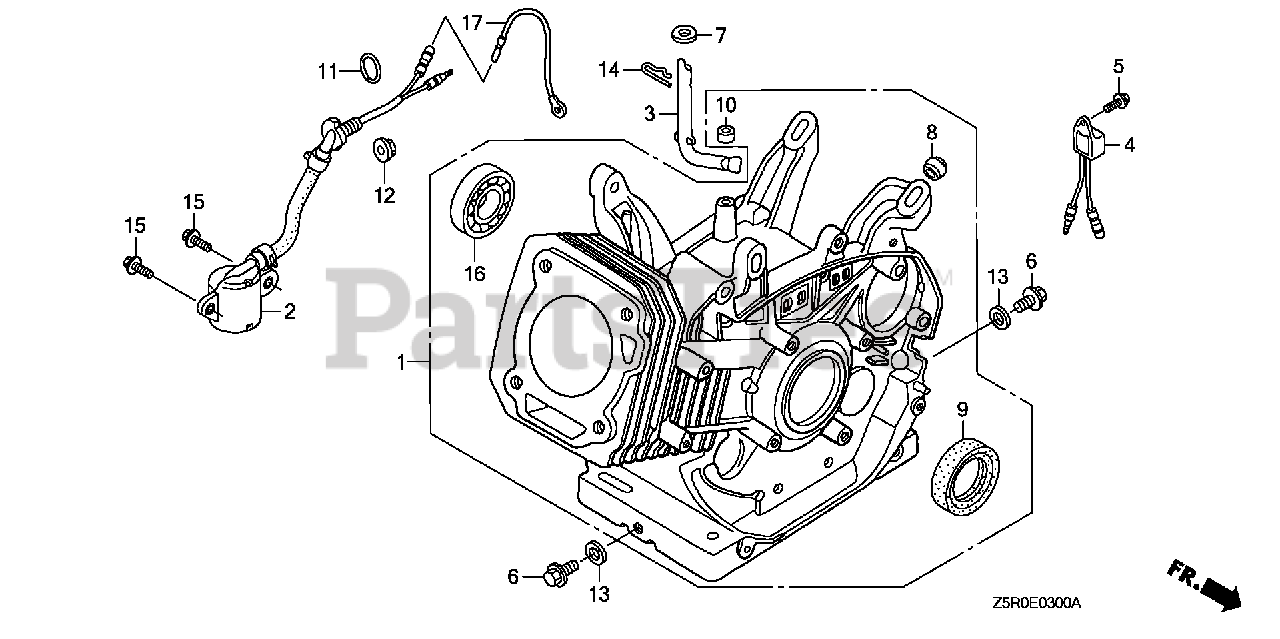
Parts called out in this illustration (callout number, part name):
1	CYLINDER ASSY. (SELF STARTER+ALERT)
2	SWITCH ASSY., OIL LEVEL
3	SHAFT, GOVERNOR ARM
6	BOLT, DRAIN PLUG
7	WASHER (8.2X17X0.8)
9	OIL SEAL (35X52X8) (NOK)
10	OIL SEAL (8X14X5)
11	O-RING (14MM) (ARAI) Use up to Engine SN 2949254.
11	O-RING (14MM) (NOK)
12	NUT, FLANGE (10MM)
13	WASHER, DRAIN PLUG (12MM)
14	PIN, LOCK (10MM)
15	BOLT, FLANGE (6X12) Use up to Engine SN 1543277.
16	BEARING, RADIAL BALL (6202)
